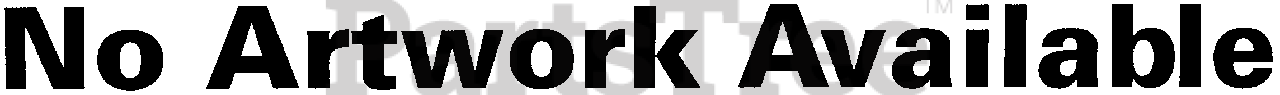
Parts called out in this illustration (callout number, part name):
2	"BOLT,HEX"
3	SCREW LT
4	"PLATE,STR SUPT"
5	GEAR SECTOR
6	BUSHING
7	NUT
8	CLIP INSULATOR
9	NUT LTV
10	COTTER PIN
11	WASHER
12	BUSHING.DRAGLINK
13	BOLT
14	WASHER
15	BOLT
16	BOLT
17	"SUPT,FRT AXLE"
18	NUT.HEX.3/8-16UNC
19	LOCKNUT
